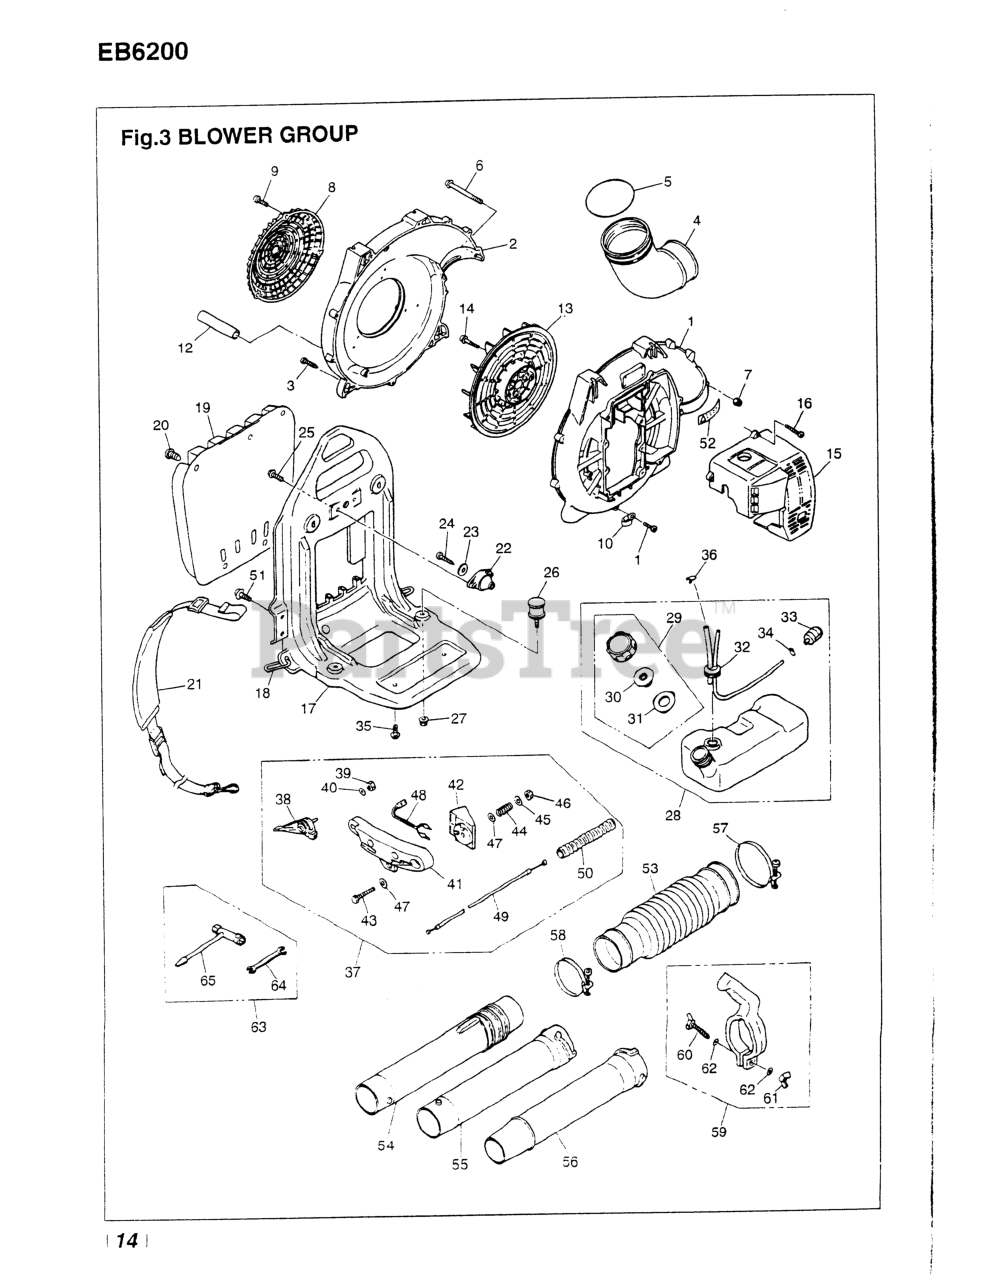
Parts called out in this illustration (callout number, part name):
2	COVER, VOLUTE
3	SCREW, M5 X 25
5	O-RING
6	SCREW, M5 X 70
7	NUT (B)
8	COVER, INLET
9	SCREW, M5 X 25
10	CLAMP
12	TUBE (USE 2750-31290)
13	FAN
14	BOLT (RPLS 3405-12211)
16	SCREW, M5 X 25
18	RING (USE -21121)
19	PAD (RPLS -21310)
20	CLIP (RPLS 3490-21320)
22	DAMPER, UPPER
23	WASHER
24	SCREW
25	BOLT, M5 X 16 (USE -32541)
26	DAMPER, LOWER
27	NUT, M6
30	VALVE, VENT
31	PACKING (RPLS -85321)
32	PIPE COMP.(RPLS 2756-85300)
33	FILTER ASSY
34	CLIP (REPLACES 2841-31280)
35	SCREW, M5 x 12
36	CLIP
37	LEVER SET
38	LEVER, THROTTLE
39	NUT (B)
40	WASHER, M5x.8(RPLS 01624-20508
42	BRACKET
43	BOLT
44	SPRING
45	WASHER
46	NUT, M6 X 5
47	WASHER, FLAT
48	SWITCH, STOP
49	CABLE, THROTTLE
50	TUBE (USE 5548-73310)
51	BOLT, M5 X 16 (USE -32541)
52	LABEL, CAUTION
54	JOINT, SWIVEL (USE 51201)
56	PIPE, END
57	2756-51510 (RPLS. 07280-09832)
59	GRIP ASSEMBLY (USE 2750-51501)
60	BOLT, WING
61	NUT, WING
62	WASHER
63	TOOL SET
64	SPANNER, 8 X 10 (RPLS 2540- )
